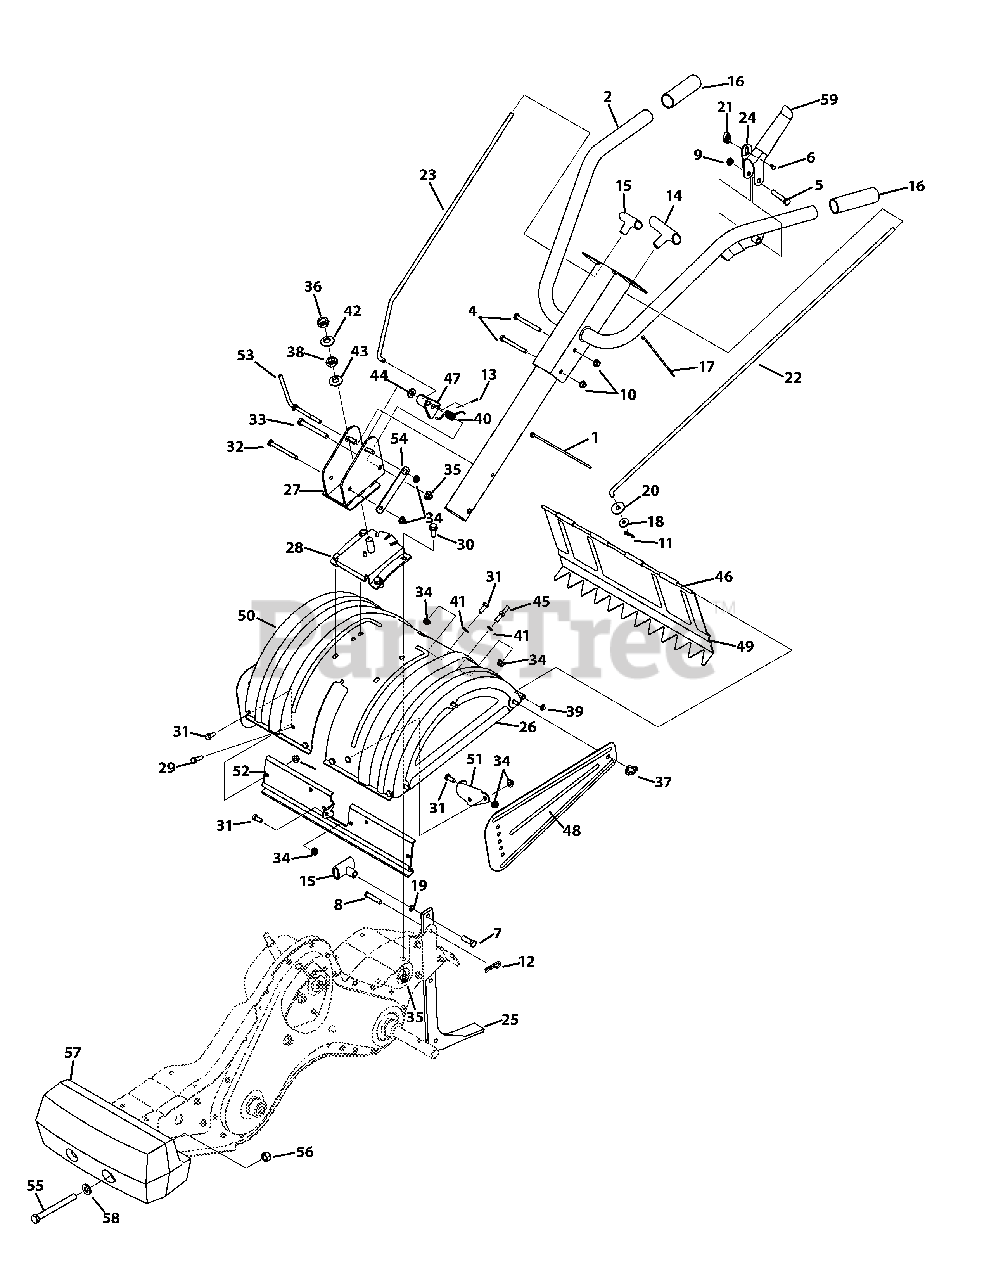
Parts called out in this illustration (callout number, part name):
1	Cable Tie
2	Upper Handle Assembly
2	Swing Handle Tube Assembly
4	Hex Screw, 5/16-18 x 3.00
5	Hex Screw, 3/8-16 x 2.50
6	Hex Screw, #10-16 x 0.440
7	Hex Screw, 3/8-16 x 1.25
8	Clevis Pin, 3/8 x 1.75
9	Flange Lock Nut, 3/8-16
10	Flange Lock Nut, 5/16-18
11	Cotter Pin, .072 x 1.13
12	Bow-Tie Cotter Pin
13	Cotter Pin, 3/32 x .750
14	T-Knob
15	T-Knob
16	Round Grip
17	Cable Tie, 3/16 x .05 x 7.4
18	Rubber Washer, .33 x .87 x .125
19	Flat Washer, .385 x .620 x .033
20	Flat Washer, .411 x 1.25 x .100
21	Cable Barrel Holder
22	Clutch Rod
23	Clutch Rod
25	Tiller Depth Control
27	Handle Pivot Bracket Assembly
28	Handle Pivot Base Bracket Assembly
29	Hex Screw, 5/16-18 x 1.00
30	Hex Washer Screw, 3/8-16 x .875
31	Hex Screw, 5/16-18 x .75
32	Hex Screw, 5/16-18 x 3.25
33	Hex Screw, 3/8-16 x 3.25
34	Flange Lock Nut, 5/16-18
35	Flange Lock Nut, 3/8-16
36	Jam Lock Nut, 5/8-18
37	Wing Nut w/ Bell Washer, 5/16-18
38	Jam Nut, 5/8-18
39	Cap Speed Nut, 1/4
40	Torsion Spring, .415 x .95
41	Flat Washer, .344 x .62 x .033
42	Flat Washer, .656 x 1.25 x .02
43	Bell Washer, .63 x 1.25 x .18
44	Flat Washer, .406 x .875 x .105
45	Hex Screw, 5/16-18 x .75
46	Tiller Flap Rod
47	Swing Handle Link
48	Side Shield
49	Rear Tine Shield
50	Tine Shield
51	Front Tine Shield Bracket
52	Front Tine Shield Scraper Bracket
53	Handle Adjustment Crank
54	Hex Flange Retainer Bracket
55	Hex Screw, 1/2-13 x 5.00
56	Flange Lock Nut, 1/2-13
57	40 lb. Counterweight
58	Flat Washer, .510 x 1.000 x .125
59	Clutch Grip
